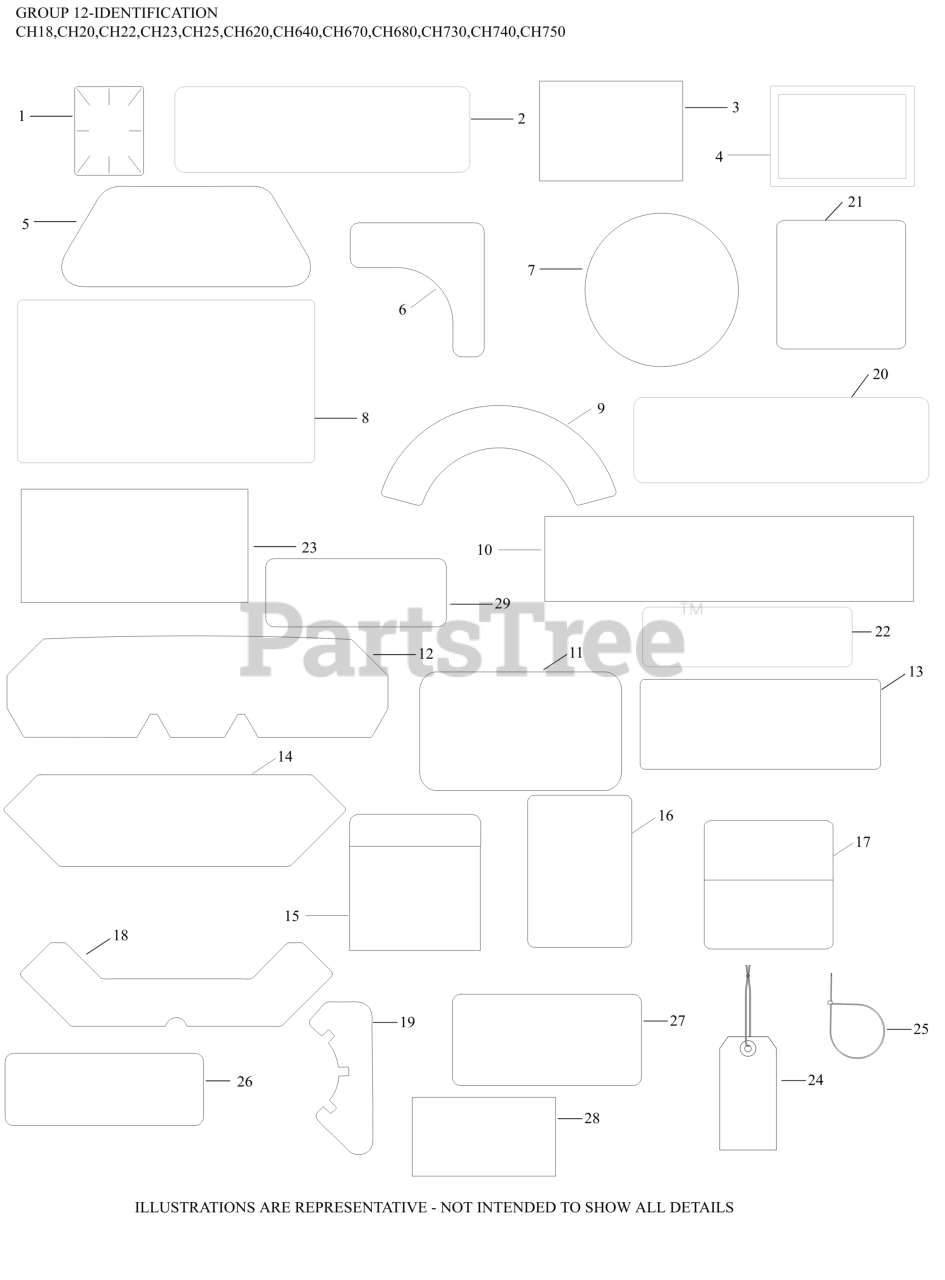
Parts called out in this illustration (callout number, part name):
2	DECAL, 25 HP
3	DECAL, OIL COOLER - DISC.
8	DECAL, AIR CLEANER - DISC.
NI	WIRE TIE USE 25 454 05-S
